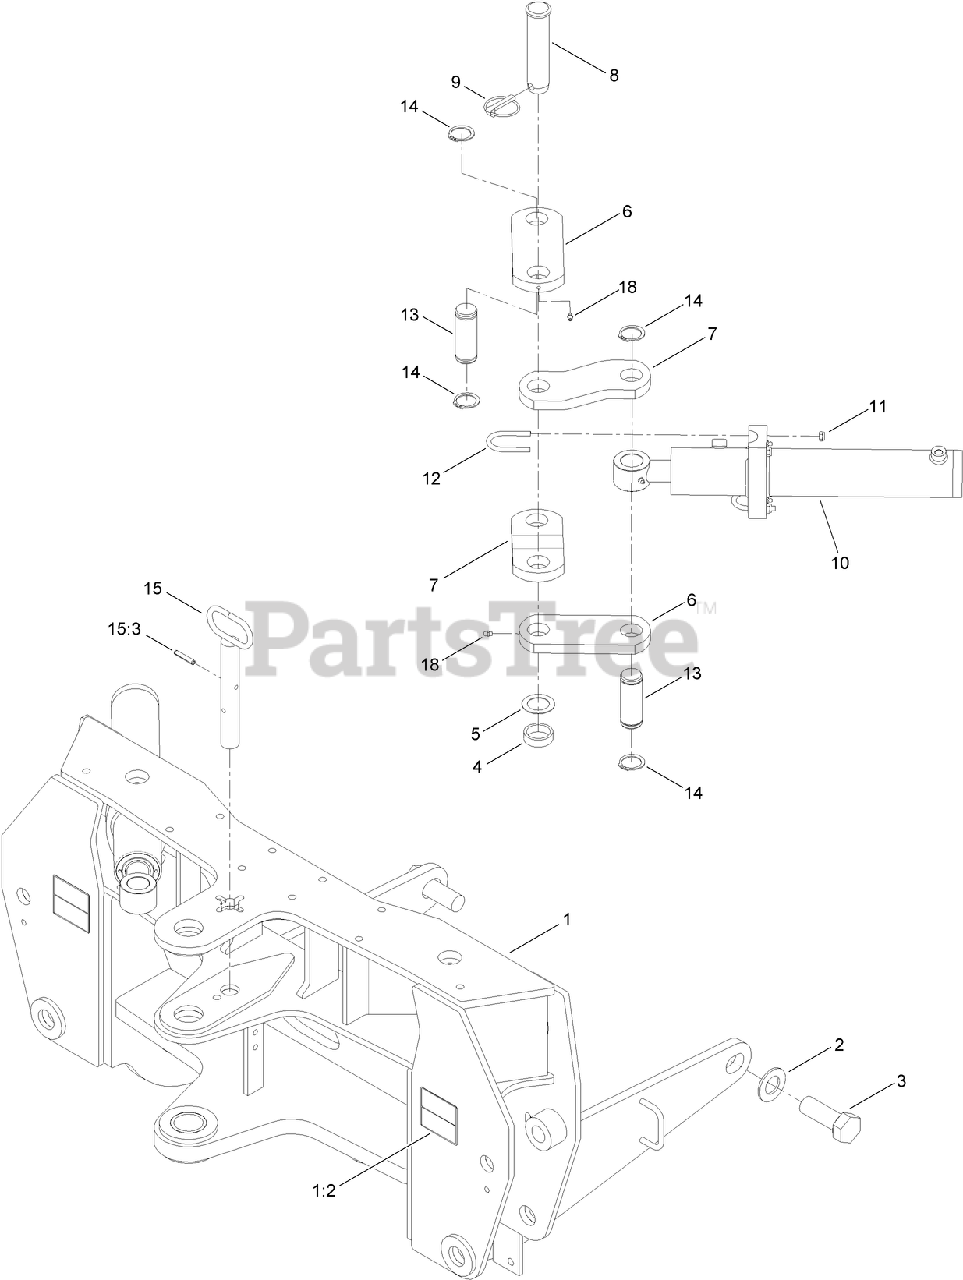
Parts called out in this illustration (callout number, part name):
1	MOUNTING FRAME ASM
1:2	DECAL-DANGER, CRUSHING
4	SPACER-LINK, SWING
5	WASHER
9	PIN-KLIK
10	HYD CYLINDER ASM
11	NUT-HEX
15	LOCKING SWING PIN ASM
15:3	PIN-SPRING, SLOTTED
18	FITTING-GREASE
